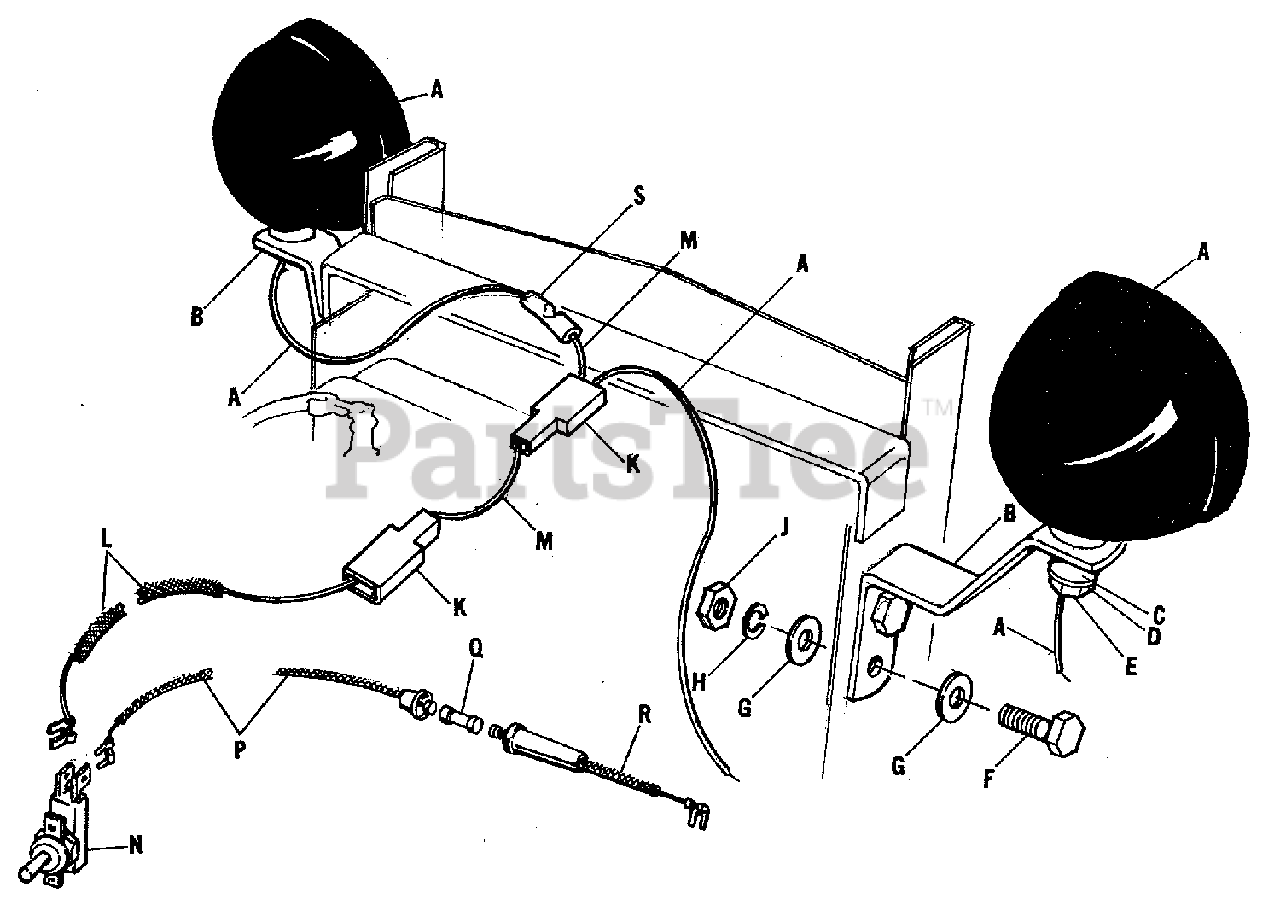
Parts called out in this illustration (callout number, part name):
A	LAMP ASSEMBLY
D	WASHER, Lock, 1/2"
E	NUT, Hex, Full, 1/2"-13
F	CAPSCREW, Hex, 5/16"-18 x 1-1/2"
G	WASHER, Plain, 5/16"
H	WASHER, Lock, 5/16"
J	NUT, Hex, Full, 5/16"-18
K	CONNECTOR, Insulated
L	WIRE (Switch To Connector)
M	WIRE, Extension
N	SWITCH, Toggle
P	WIRE (Fuse To Switch)
Q	FUSE, 20 Amp.
R	WIRE (Fuse To Voltage Regulator
S	CONNECTOR
